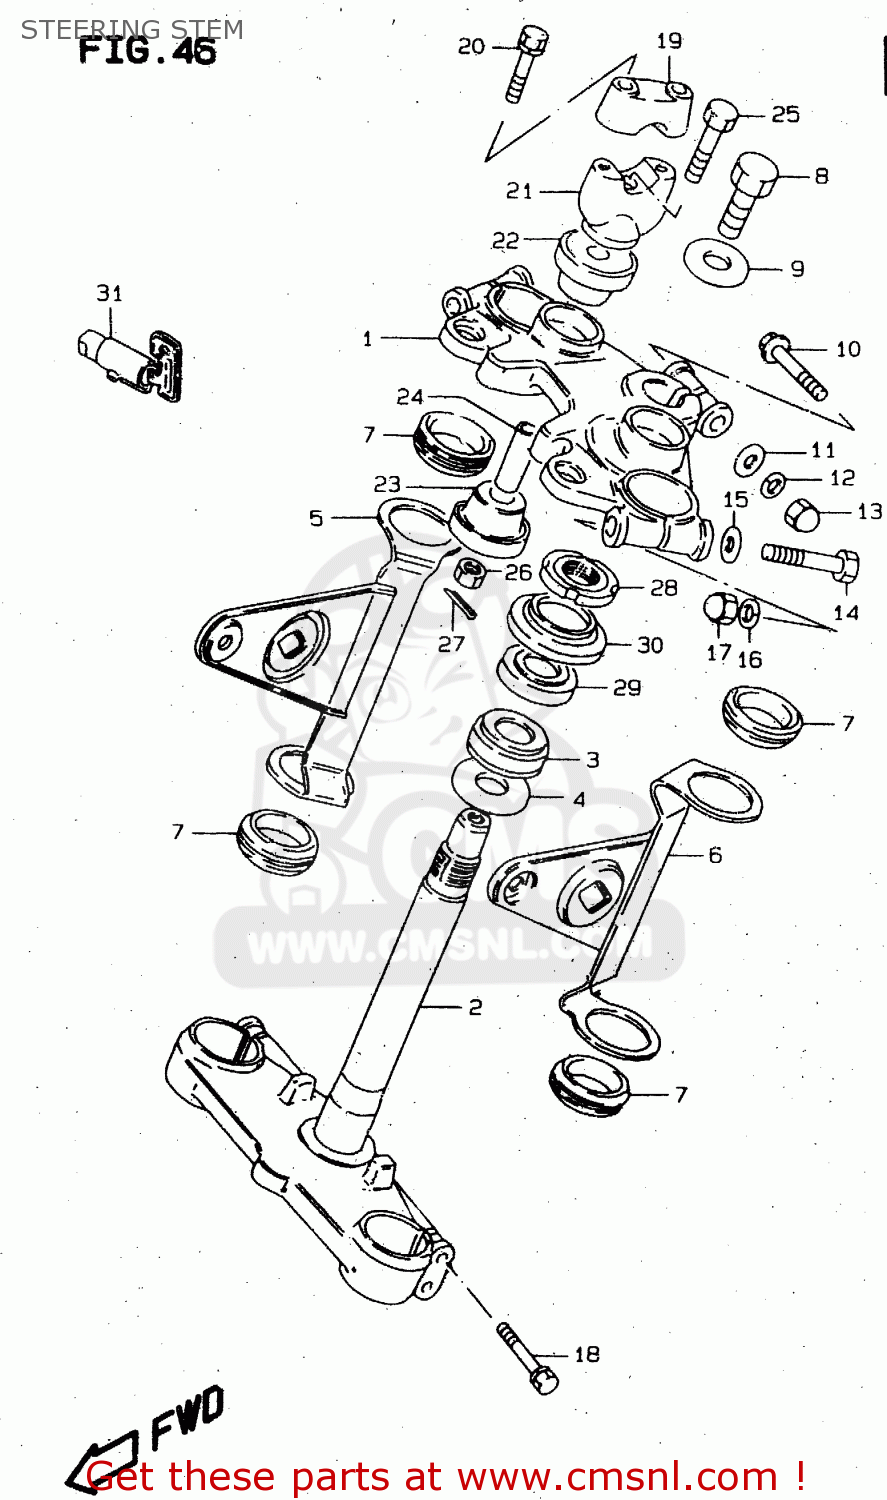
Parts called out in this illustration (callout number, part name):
1	HEAD,STEERING STEM
2	STEM SET,STEERING
3	BEARING(30X55X17)
4	SHIM(30X40X1.5)
5	BRACKET,HEADLAMP,R
6	BRACKET,HEADLAMP,L
7	CUSHION,HEADLAMP BRACKET
8	BOLT(12X20)
9	WASHER(12.5X26X1.6)
10	BOLT, LH
11	WASHER
12	LOCK WASHER
13	NUT
14	BOLT 10X55
15	WASHER
16	WASHER
17	NUT
18	BOLT
19	HOLDER,HANDLE UPR
20	BOLT
21	HOLDER,HANDLEBAR LWR
22	CUSHION,UPR
23	CUSHION,LWR
24	SPACER(10.2X14X46)
25	BOLT(10X78)
26	NUT
27	COTTER PIN
28	NUT,STEERING STEM(25X44X10)
29	BEARING(25X47X15)
30	SEAL,STEERING UPR DUST
31	LOCK ASSY,STEERING(NEIMAN)
